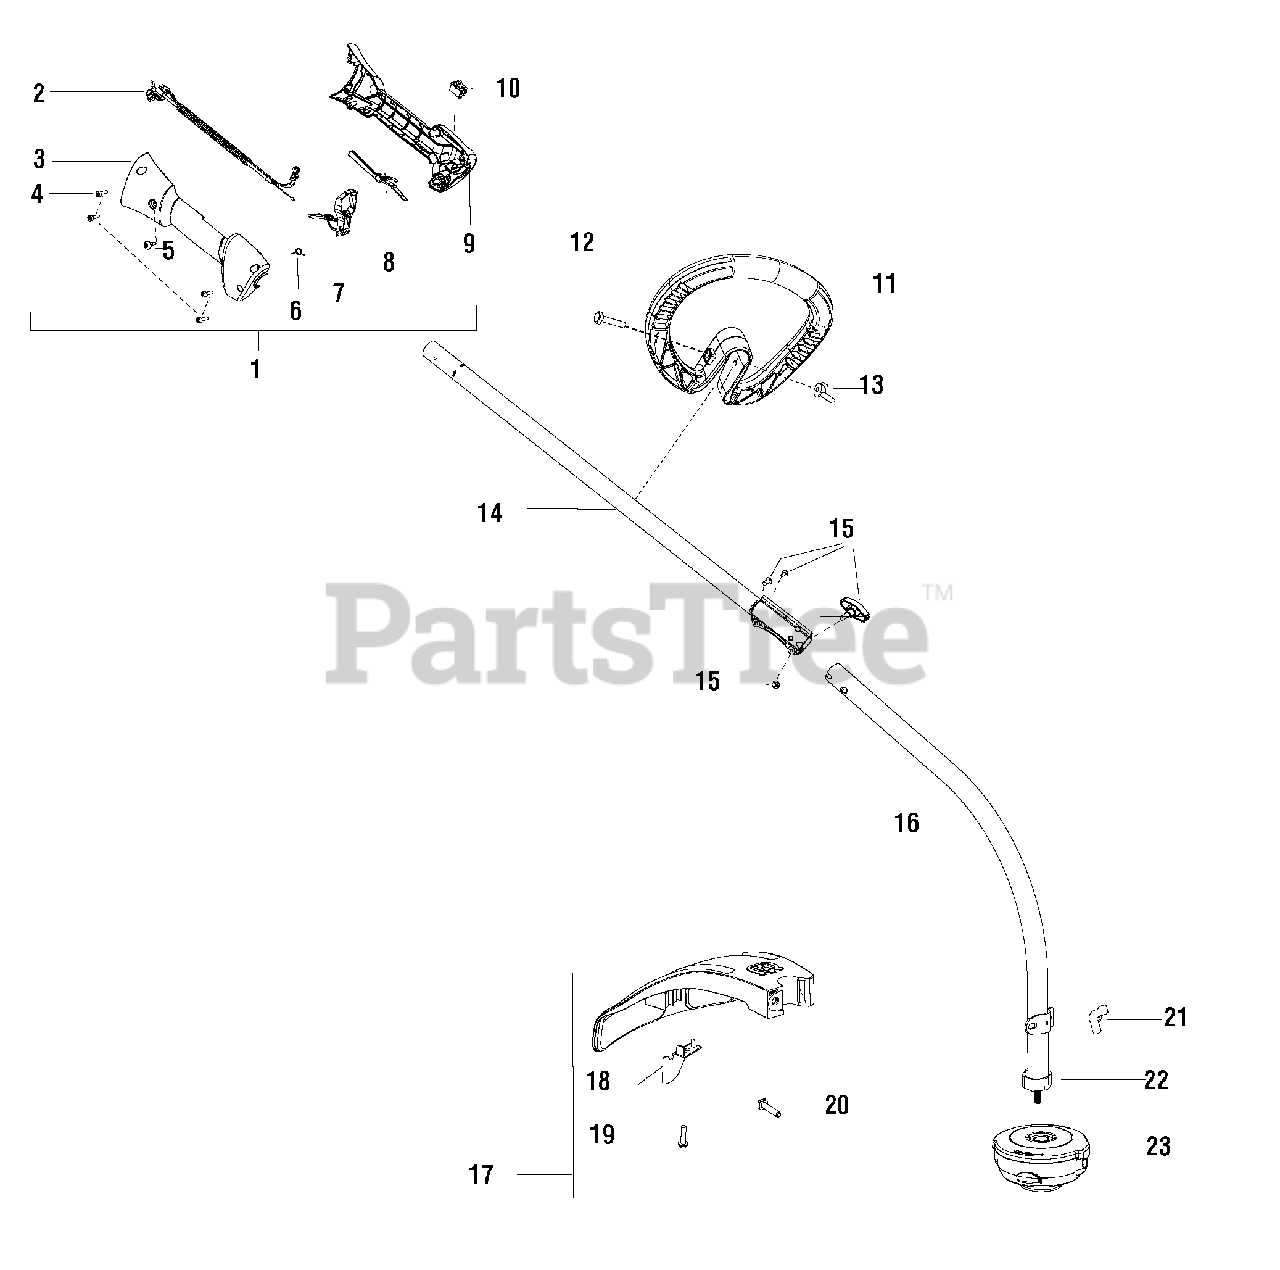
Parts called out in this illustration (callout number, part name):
1	Assy - Throttle Housing
2	Assy - Cable/Wire Harness
3	Housing-Throttle, RH
4	Screw
5	Screw
6	Spring-Trigger
7	Trigger
8	Lockout-Throttle
9	Housing-Throttle, LH
10	Kit-Switch
11	Handle - Assist
13	Wingnut
14	Assy-Driveshaft Upper
15	Kit - Knob / Screw
16	Kit - Lower Shaft
17	Kit - Shield
18	Limiter - Line
19	Screw
21	Wingnut
22	Dust Cup
23	Head - Cutting
